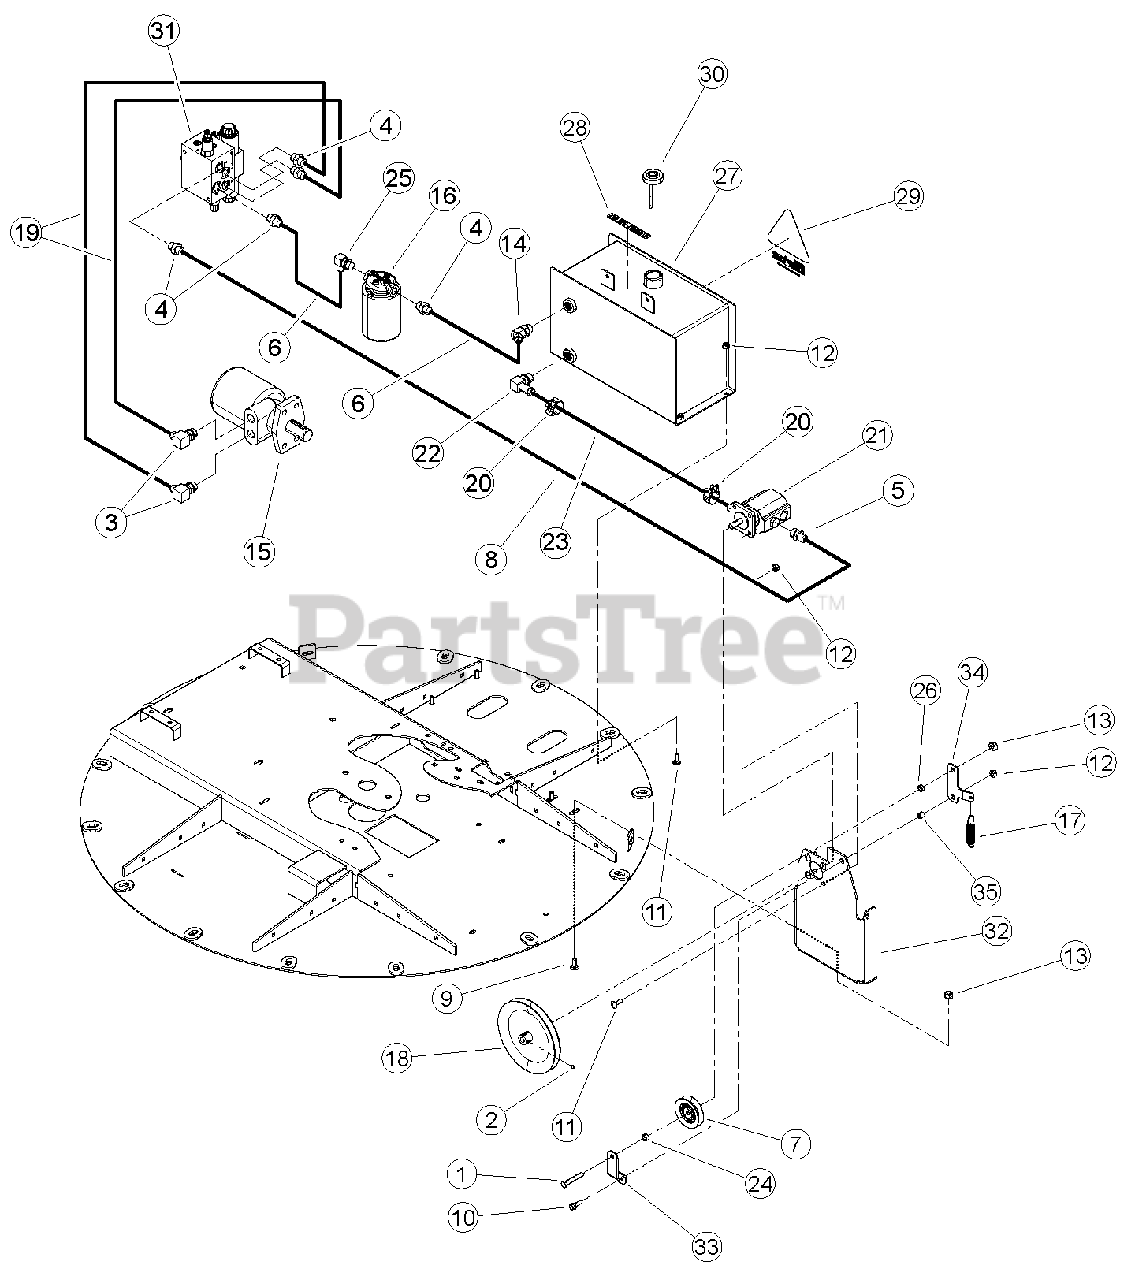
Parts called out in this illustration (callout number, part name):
1	BOLT, 3/8 X 2-1/4 HEX GR5 ZP
2	SET SCREW, HSC 1/4 -20X -3/8 CUP
3	ADAPTER, -10MORING/-8MJIC 90 DEG
4	ADAPTER, -8MORING/-8MJIC
5	ADAPTER, -10MORING/-8MJIC
6	HOSE ASSEMBLY, 8FMJIC/8FMJIC SW X 32"
7	IDLER, INSIDE
8	HOSE ASSEMBLY, 8FJIC90 SW X 8FJIC SW 54"
9	BOLT, 3/8 X 1" GR5 CRG NC ZP
10	BOLT, 5/16 X 1 FLANGE NC
11	BOLT, 5/16 X 1" GR5 CRG ZP
12	NUT, 5/16-18 NYLOCK-FLANGE
13	NUT, 3/8-16 NYLOCK FLANGE
14	ADAPTER, -10MORING/-8MJIC 45 DEG
15	MOTOR, 45 CU IN HYDRAULIC
16	ASSEMBLY, HYDRAULIC FILTER
17	SPRING, 3/4" OD EXTENSION
18	PULLEY, 7.5 OD X 1/2 IN BORE
19	HOSE ASSEMBLY, -8FMJIC/-8FMJIC90 X 61
20	CLAMP, 1-5/32 TO 7/32 OD RANGE T-BOLT
21	PUMP, 2 STAGE CW HI/LO 0.605 DISP.
22	ADAPTER, -10 MORING/.75 90 DEG HOSE
23	HOSE, .75 X 19.75 100R4
24	BUSHING
25	ADAPTER, -8MORING/-8MJIC 90 DEG
26	SPACER, IDLER PIVOT
27	ASSEMBLY, HYDRAULIC TANK SERVICE PART
28	DECAL, HYDRAULIC FLUID
29	DECAL, CHIP IT (WHITE)
30	CAP, HYDRAULIC W/ DIPSTICK
31	ASSEMBLY, HYDRAULIC FEED FLOW VALVE W/ PS
32	WELDMENT, PUMP MOUNT
33	BRACKET, IDLER MOUNT
34	PLATE, IDLER MOUNT
35	SPACER, 1/2 OD X 14 GA X .49
